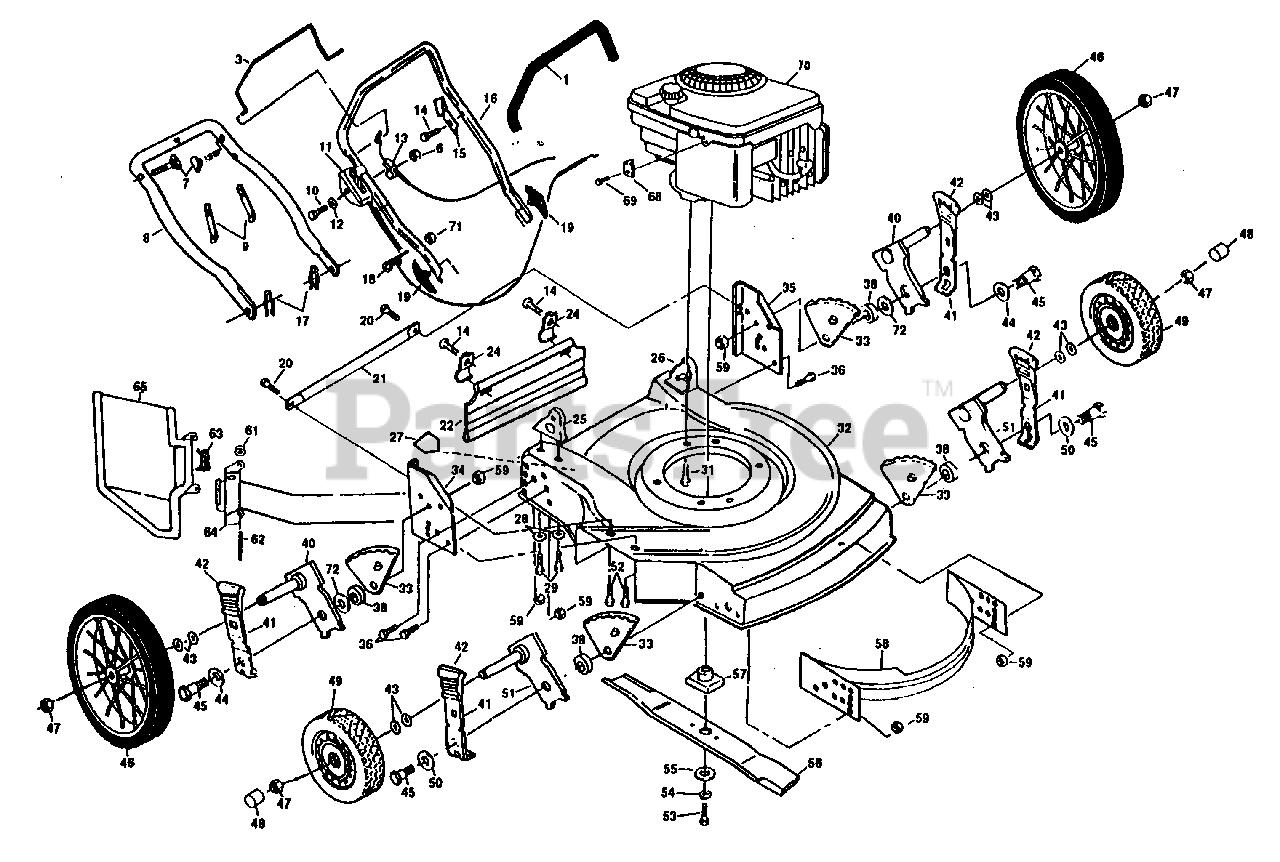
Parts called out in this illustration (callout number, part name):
1	Handle Grip (AYP part number)
3	Control Bar (AYP part number)
6	Locknut 1/4-20 (AYP part number)
7	Handle Bolt 5/16-18 x 1-3/4 (AYP part number)
8	Lower Handle (AYP part number)
9	Wire Tie (AYP part number)
10	Machine Screw 1/4-20 x 2-1/8 (AYP part number)
11	Throttle Control
12	Washer (AYP part number)
13	Engine Zone Control Cable
14	Hex Washer Head Screw #10-24 x 1/2 (AYP part number)
15	Up-Stop Bracket (AYP part number)
16	Upper Handle (AYP part number)
17	Hairpin Cotter (AYP part number)
18	Rope Guide
19	Handle Knob (AYP part number)
20	Self-tapping Screw 1/4-20 x 1/2 (AYP part number)
21	Support Rod (AYP part number)
22	Rear Skirt (AYP part number)
24	Skirt Bracket (AYP part number)
25	Handle Bracket Assembly (Right) (AYP part number)
26	Handle Bracket Assembly (Left) (AYP part number)
27	Danger Decal (AYP part number)
28	Washer (AYP part number)
29	Thread Cutting Screw 5/16-18 x 1-3/4 (AYP part number)
31	Thread Rolling Screw 3/8-16 x 1 (AYP part number)
32	Lawn Mower Housing
33	Wheel Adjusting Bracket (AYP part number)
34	Wheel Support Bracket (Right) (AYP part number)
35	Wheel Support Bracket (Left) (AYP part number)
36	Hex Head Bolt 3/8-16 x 3/4 (AYP part number)
38	Spacer (AYP part number)
40	Axle Arm Assembly (Rear) (AYP part number)
41	Selector Spring (AYP part number)
42	Selector Knob
43	Washer (AYP part number)
44	Washer (AYP part number)
45	Shoulder Bolt 3/8-16 (AYP part number)
46	Wheel & Tire Assembly (AYP part number)
47	Locknut (AYP part number)
48	Hubcap (AYP part number)
49	Wheel & Tire Assembly
50	Washer (AYP part number)
51	Axle Arm Assembly (Front) (AYP part number)
52	Hex Screw W/Sems 1/4-20 3/8 (AYP part number)
53	Hex Head Screw 3/8-24 x 1-3/8 Gr. 8
54	Helical Washer 3/8 (AYP part number)
55	Hardened Washer (AYP part number)
56	22" Blade
57	Blade Adapter (AYP part number)
58	Front Baffle & Rear (AYP part number)
59	Locknut 3/8-16 (AYP part number)
61	Speed-Nut (AYP part number)
62	Hinge Rod (AYP part number)
63	Torsion Spring (AYP part number)
64	Housing Bracket Assembly (AYP part number)
65	Discharge Guard
68	Cable Clamp (AYP part number)
69	Thread Rolling Screw #10-32 x 5/8 (AYP part number)
71	Locknut, Keps 1/4-20 (AYP part number)
72	Flat Washer 3/8 (AYP part number)
